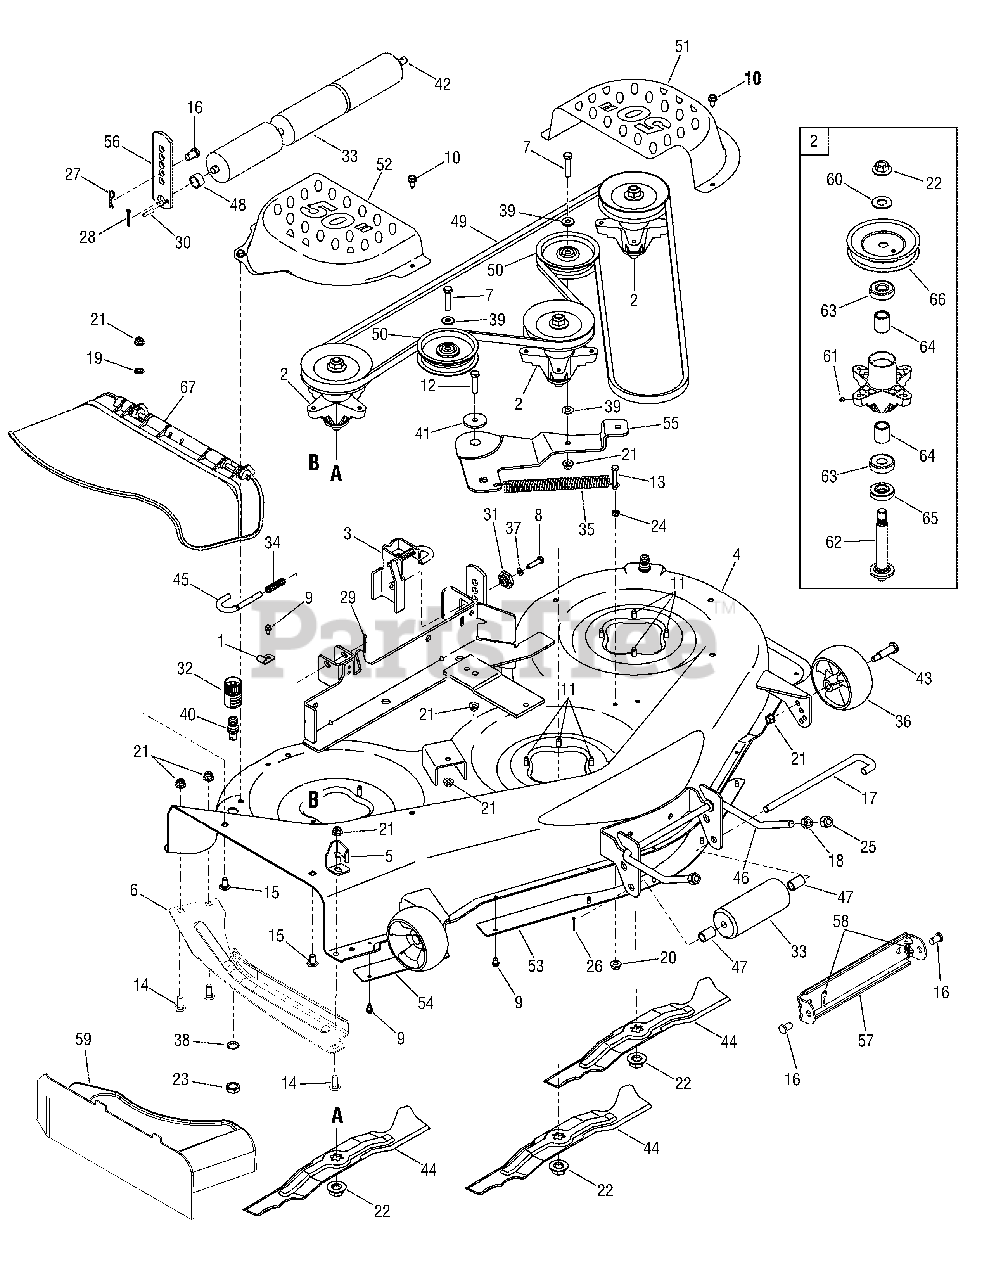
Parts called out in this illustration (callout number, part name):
1	Bracket, Hook Retainer
2	Spindle Assembly
7	Screw, Hex Cap, 3/8-16 x 1.75 Gr5
8	Screw, Hex Cap, 5/16-18 x 1.25 Gr5
9	Screw, Hex Wash. Hd. Tapp, 1/4-20 x .5
10	Screw, Hex Wash. Hd. Tapp, 5/16-18 x .5
11	Screw, Hex Wash. Hd. Tapp, 5/16-18 x .75
12	Screw, Hex Cap, 3/8-16 x 1.25 Gr5
13	Screw, Hex Cap, 5/16-18 x 2.0 Gr5
14	Screw, Carriage, 3/8-16 x 1.0
15	Screw, Carriage, 3/8-16 x .75
16	Pin, Clevis, .5 x .78
17	Pin, Roller, .5 x 10.06
18	Nut, Hex, 1/2-13 Gr5
19	Nut, Push, 3/8
20	Nut, Hex Flange Insert Lock, 5/16-18 GrF
21	Nut, Hex Flange Insert Lock, 3/8-16 GrF
22	Nut, Hex Flange, 5/8-18
23	Nut, Hex, M16-1.5
24	Nut, Hex, 5/16-18 Gr5
25	Nut, Hex Insert Lock, 1/2013
26	Pin, Cotter, 3/32 x 1.0
27	Pin, Click, .092 x 1.64
28	Pin, Cotter, 5/32 x 1.25
29	Pin, Cotter, 1/8-1.25
30	Pin, Spring, 1/4 x 1.0
31	Gear, Deck Adjust
32	Adapter, Water Nozzle
33	Roller, Front
34	Spring, Compression, .531 x 1.75
35	Spring, Extension, .94 x 6.74
37	Washer, Lock, 5/16
38	Washer, Internal Tooth Lock, 5/8
39	Washer, Flat, .406 x .875 x .059
40	Nozzle, Deck Wash
41	Spacer, Shoulder, .884 x .190
42	Shaft, .5 x 20.8
43	Bolt, Shoulder, .496 x 2.5:3/8-16
44	Blade, 2 in 1 Star, 17.9
45	Rod, Deck Release
46	Rod, Deck Front Hanger
47	Spacer, .55 x .75 x 1.125
48	Spacer, .542 x .75 x .5
49	V-Belt, B Sec., 134 in.
50	Pulley, Idler, 4.25 Dia.
58	Pin, Internal Cotter
59	Plug, Mulch
60	Washer, Flat, .76 x 1.5 x .12
61	Fitting, Lube
62	Shaft, Spindle
63	Bearing, Ball
64	Spacer, .80x 1.10 x 1.322
65	Spacer, .79 x 1.84 x .55
66	Pulley, Deck
67	Chute Assembly, Discharge
67	Pin, Hinge, .3125 x 14.06
67	Spring, Torsion, .44 x 2.1
67	Bracket, Chute Mounting
